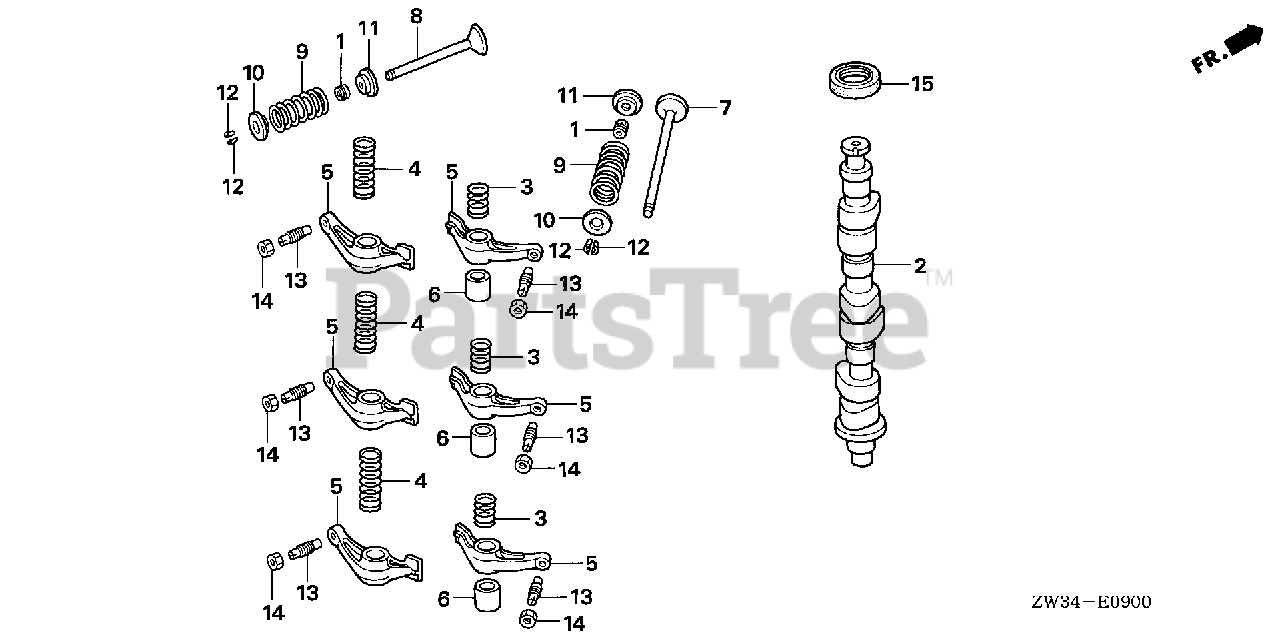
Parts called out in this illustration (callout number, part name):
1	SEAL, VALVE STEM
3	SPRING, ROCKER ARM A
4	SPRING, ROCKER ARM B
5	ARM, IN. ROCKER
6	COLLAR, ROCKER
7	VALVE, IN.
8	VALVE, EX.
9	SPRING, VALVE
10	RETAINER, VALVE SPRING
11	SEAT, VALVE SPRING
12	COTTER, VALVE
13	SCREW, TAPPET ADJUSTING
14	NUT, TAPPET ADJUSTING
15	OIL SEAL (30X42X8)
